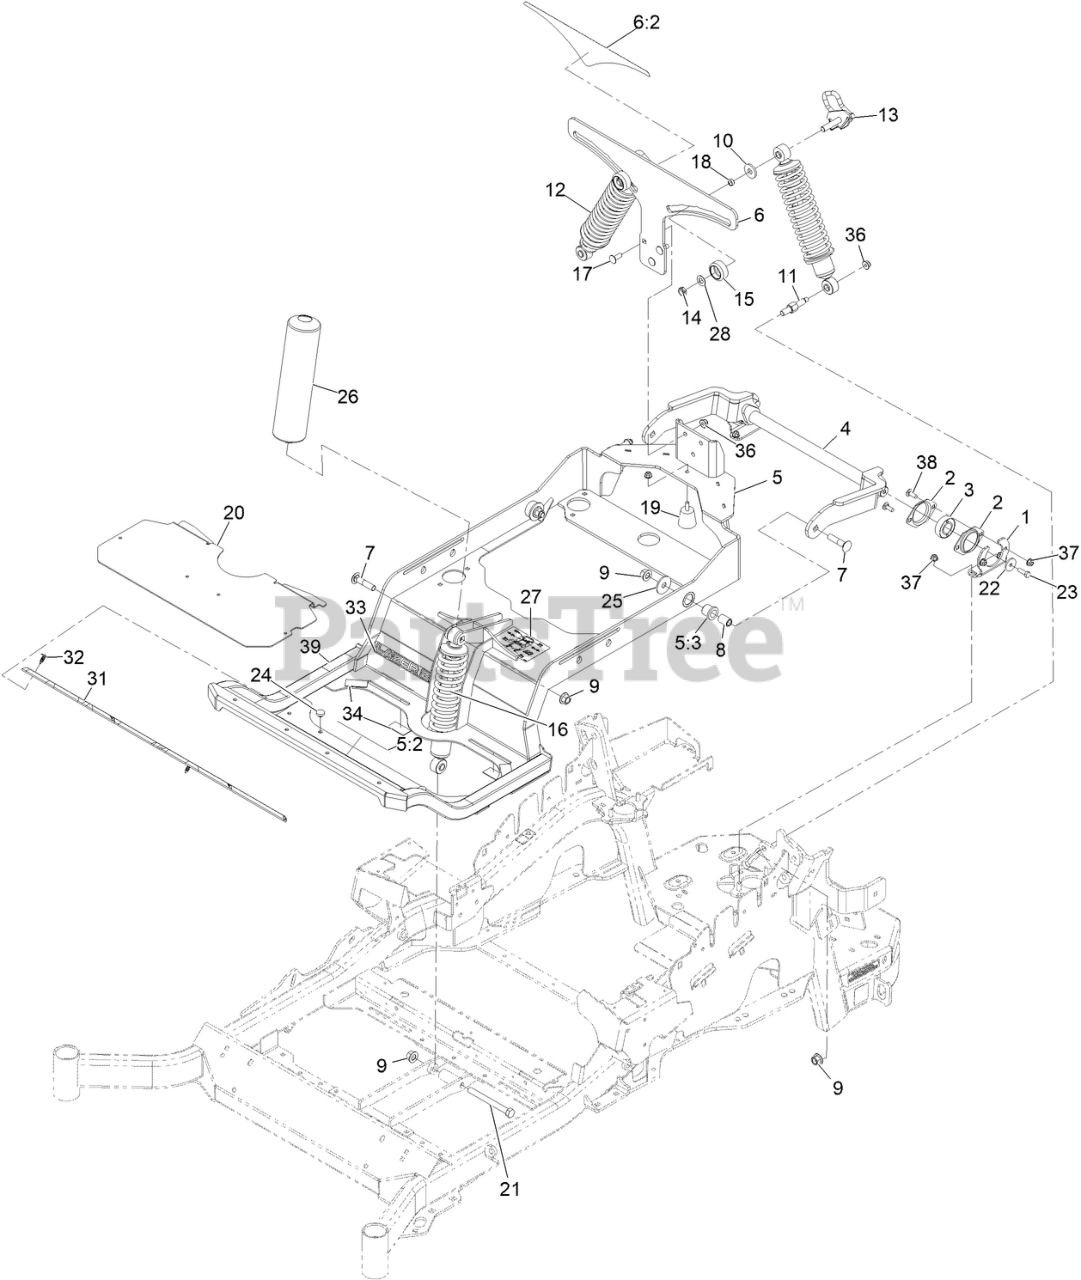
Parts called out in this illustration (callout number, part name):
1	BRACKET-BEARING
2	HOUSING-BEARING, FLANGE
3	BEARING
4	ARM-TRAILING
5	Subframe ASM
5:2	DECAL-DANGER
5:3	BUSHING-FLANGE
6	Bracket-Mounting
6:2	DECAL-ADJUSTMENT, RIDE
7	SCREW-CARR
8	SPACER-ALUMINUM
9	Nut-Lock 1/2-13
10	WASHER-PLASTIC
11	BOLT-SHOULDER
12	SHOCK/SPRING ASM
13	Cam Lock ASM
14	NUT-HEX
15	KNOB-LOCK, CAM
16	SHOCK ASM-FRONT
16	SHOCK/SPRING ASM
17	SCREW-CARR
18	BEARING-SLEEVE
19	BUMPER-RUBBER
21	SCREW-HH
22	WASHER-FLAT
23	SCREW-HH, THREAD LOCKING
25	WASHER-THRUST
26	COVER-SHOCK
27	DECAL-SERVICE AID
28	WASHER-ADJUSTING
31	FLOOR MAT
32	PLUG-PLASTIC
33	DECAL-LAZER LOGO
34	PAD-RUBBER
36	NUT-HF, NI
37	NUT-HF, NI
38	BOLT-CARR
39	DECAL-BRAKE, PARKING
